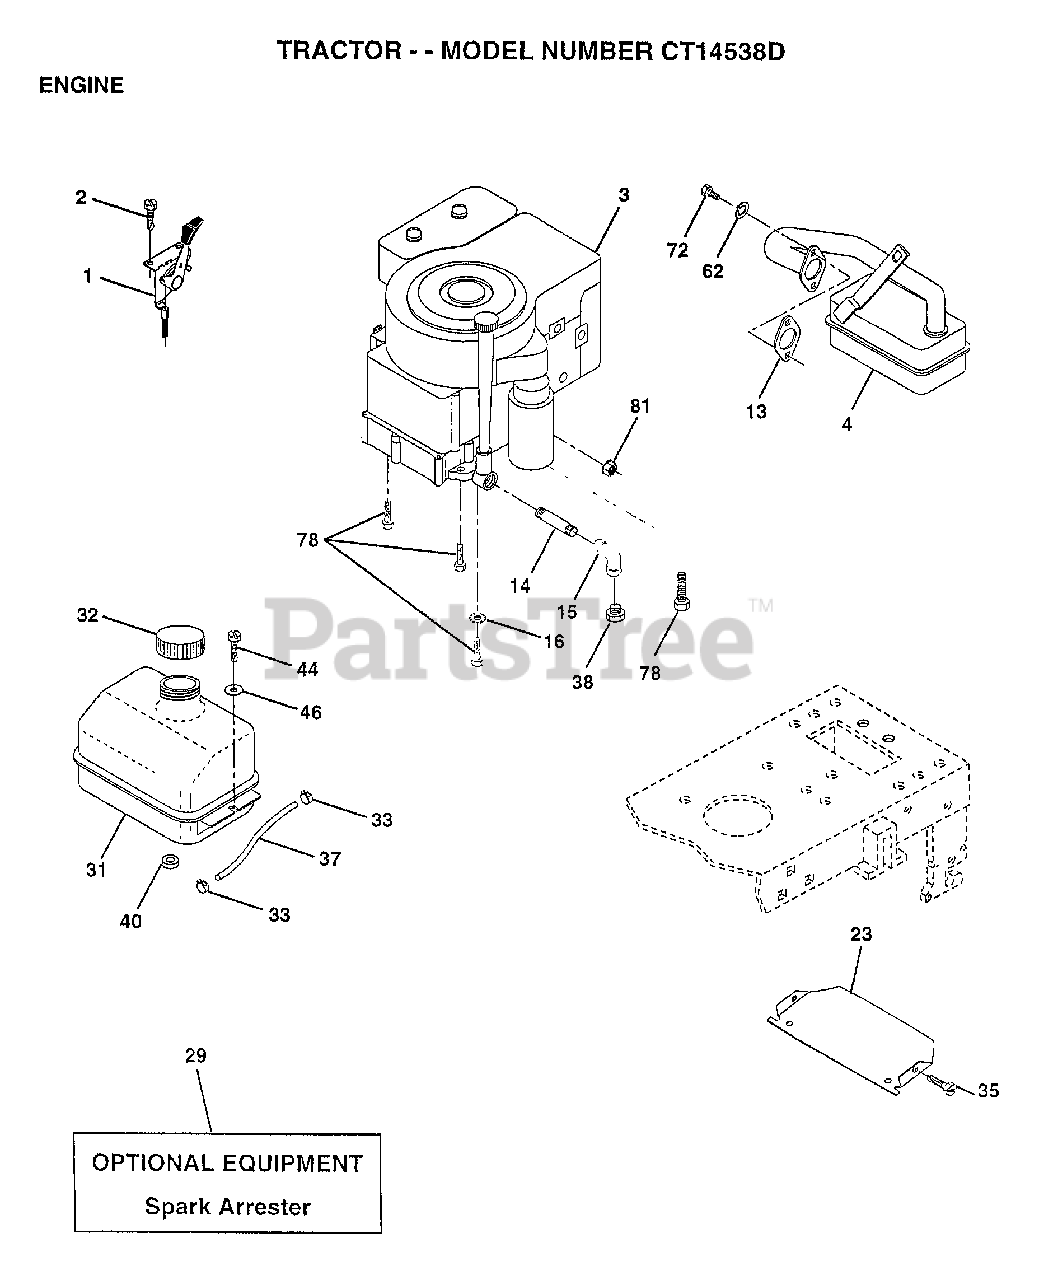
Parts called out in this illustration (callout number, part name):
1	THROTTLE CONTROL
2	SCREW LT
4	MUFFLER
13	GASKET ENG 1 313 LD TIN PLATED
14	PIPE NIPPLE
15	ELBOW
16	LOCKWASHER
23	SHIELD-HEAT
31	TANK.FUEL.LT.
32	CAP ASM FUEL
33	HOSE CLAMP
35	SCREW
37	LINE FUEL
44	SCREW HEX CRT
46	WASHER
62	LOCKWASHER
72	SCREW
78	SCREW
81	NUT
